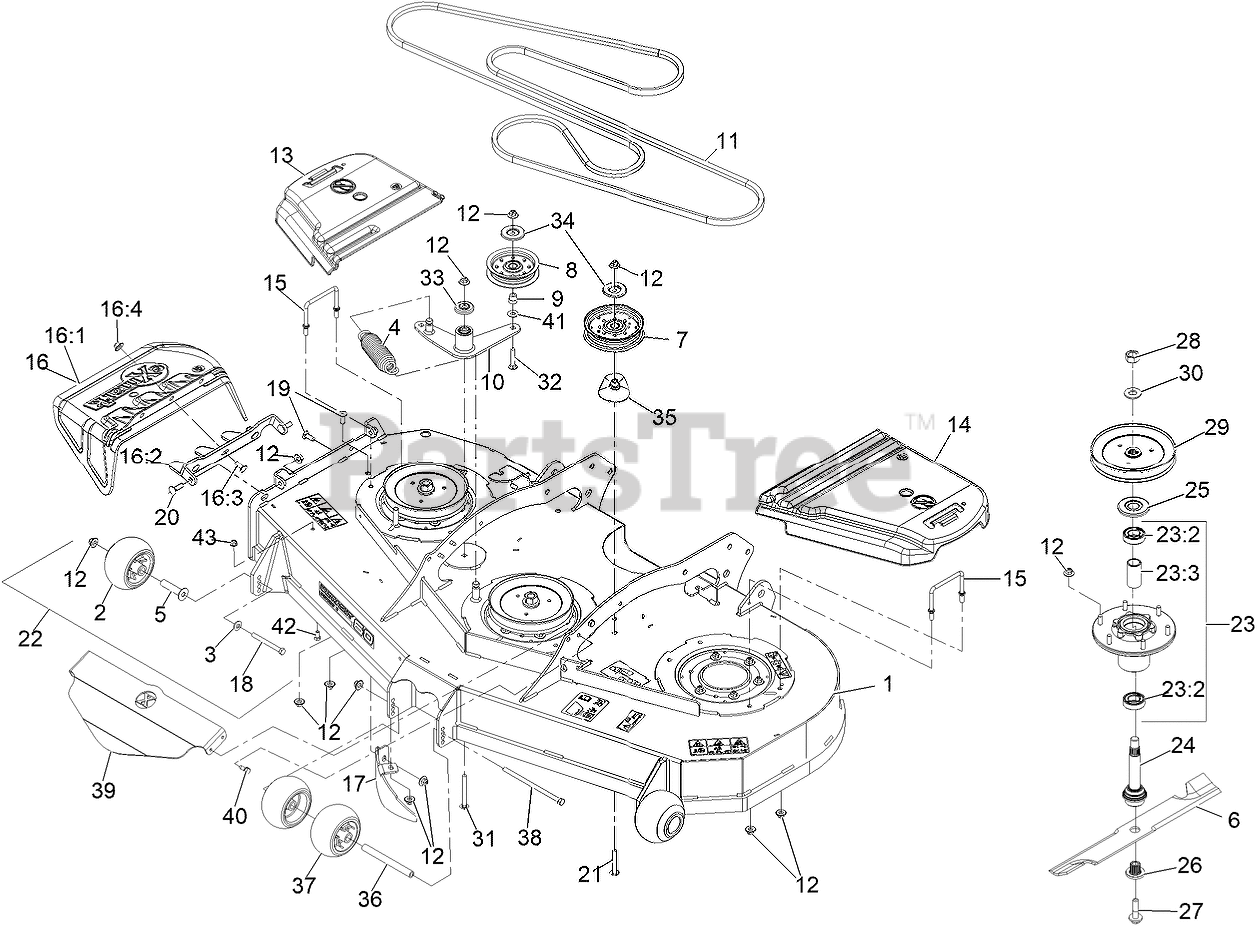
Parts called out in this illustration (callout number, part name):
1	ASM-DECK W/DECALS 604
2	ROLLER-SCALP, ANTI
3	WASHER-BELLEVILLE
4	SPRING-EXTENSION
5	AXLE, ROLLER
6	Blade-Extreme 2, 20.50"
7	PULLEY-IDLER, FLAT
9	BUSHING,IDLER
10	IDLER ARM ASM W/BEARINGS
11	BELT-V
12	Nut-Nyloc 3/8-16 Flg
13	COVER-BELT, RH
14	COVER-BELT, LH
15	WIREFORM-COVER
16	ASM,DISCHARGE CHUTE
16:1	CHUTE,DISCHARGE
16:2	BRACKET,DISCHARGE CHUTE
16:3	SCREW-CARR
16:4	Nut-Nyloc 3/8-16 Flg
17	DOGLEG - LZ60
18	SCREW-HH 3/8-16 X 3 3/4 GR 8
19	SCREW-CARR
20	BOLT-CARR
21	SCREW-CARR
22	KIT, ANTI-SCALP ROLLER
23	ASM-CUTTER HSG WITH BEARINGS
23:2	BEARING-BALL
23:3	SPACER-BEARING
24	ASM-SPINDLE AND SEAL
25	GUARD,BEARING TOP .989
26	BUSHING,SPLINED
27	SCREW,SEMS 1/2-20 X 2.19
28	NUT-HEX
29	SHEAVE,BLADE DRIVE 7.25
31	SCREW-CARR
32	SCREW-CARR
33	GUARD-TOP
34	SHIELD-DUST
35	SPACER-PULLEY
36	SPACER-WHEEL
37	ROLLER-SCALP, ANTI
38	SCREW-HH
39	Guard-Front Deck
40	SCREW-THD ROLL, HWH
41	WASHER-FLAT
42	SCREW-HH
43	NUT-HF, NI
